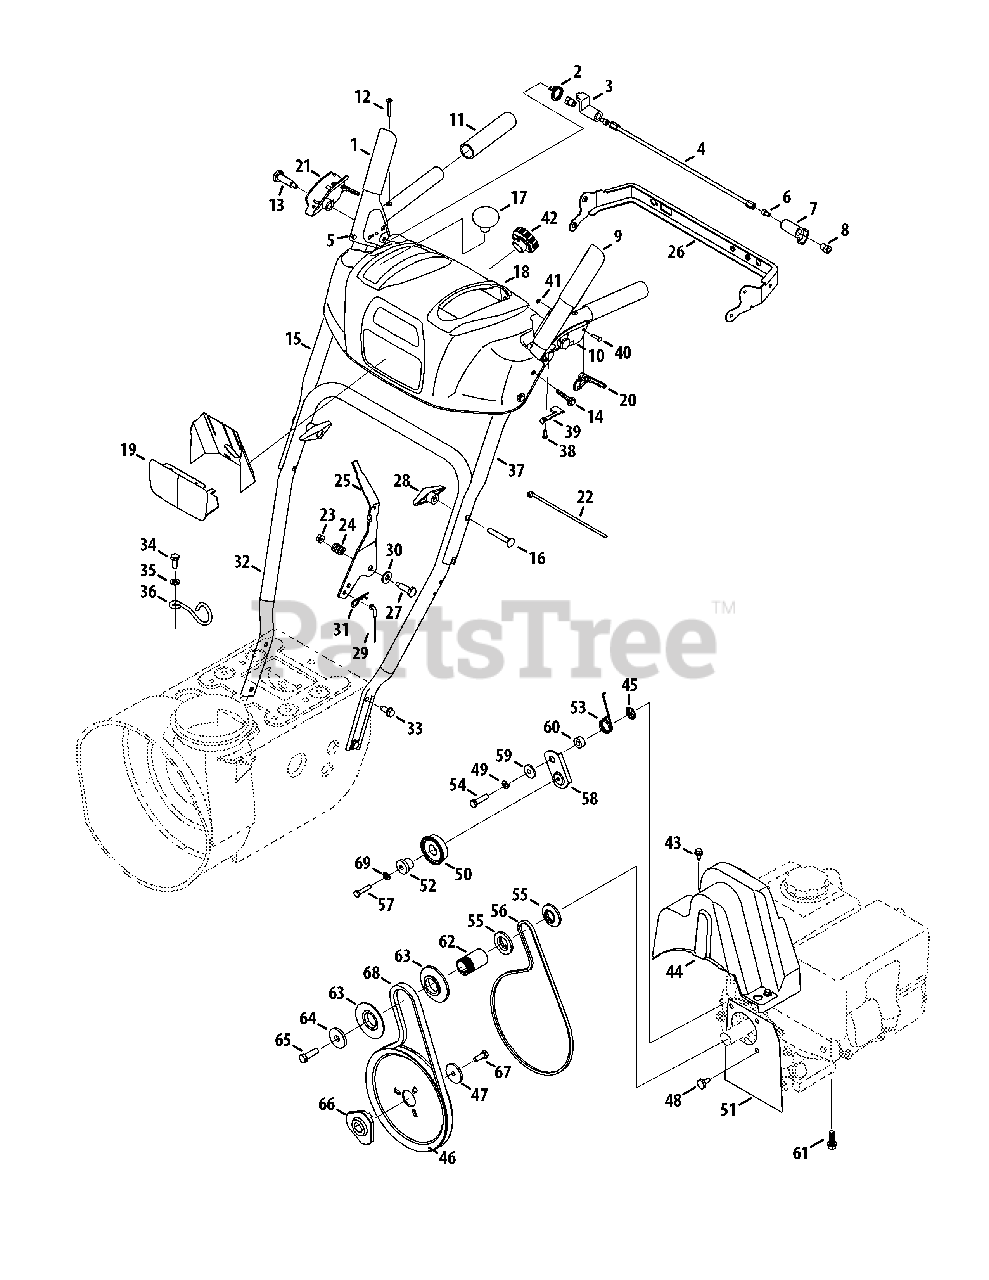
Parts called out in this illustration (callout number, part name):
1	Handle Engagement Ass’y RH
2	Torsion Spring
3	Lock Plate
4	Pivot Rod
5	Rubber Bumper
6	Screw, 1/4-20 x .500
7	Clutch Lock Cam
8	Shoulder Nut, 1/4-20
9	Handle Engagement Assembly LH
10	Handle Clutch Lock LH Assembly
11	Handle Grip
12	Screw, #10-24 x 0.375
13	Shoulder Screw, 1/4-20
14	Screw, 1/4-20 x 1.625
15	Upper Handle RH
16	Carriage Screw, 5/16-18 x 2.25
17	Shift Knob
18	Handle Panel
20	Steering Control
21	Handle Clutch Lock RH Assembly
22	Cable Tie
23	Flange Lock Nut, 1/4-20
24	Compression Spring
25	Shift Lever
26	Panel Bracket
27	Shoulder Screw
28	Wing Knob
29	Speed Selector Cable
30	Flat Washer
31	Click Pin
32	Lower Handle
33	Screw, 5/16-18 x 0.75
34	Screw, M8-1.25
35	Flat Washer, .330 x .630 x .0635
36	Cable Control Wire
37	Upper Handle LH
38	Screw, #8-16 x 0.50
39	Clutch Lock Spring
40	Pin, 3/16
41	Retainer Ring
42	Headlight Socket
43	AB Screw, 1/4-20 x 0.625
44	Belt Cover
45	Push-on Nut
46	Auger Pulley
47	Flat Washer
48	Shoulder Screw
49	Lock Washer
50	Idler Pulley Assembly
51	Plt., Cvr.
52	Spacer
53	Torsion Spring
54	Hex Screw, 5/16-24 x 1.25
55	Pulley Half
56	Belt, Wheel Drive
57	TT Screw, 1/4-20 x 1.25
58	Drive Clutch Idler Bracket
59	Shoulder Spacer
61	TT Sems Screw, 3/8-16 x 1.0
62	Spacer
63	Pulley Half
64	Flat Washer
65	Hex Bolt, 3/8-24 x 1.25
66	Pulley Adapter
67	Hex Bolt, 5/16-24 x 0.875
68	V-Belt,.500 x 35.00 Lg
69	Lock Washer
